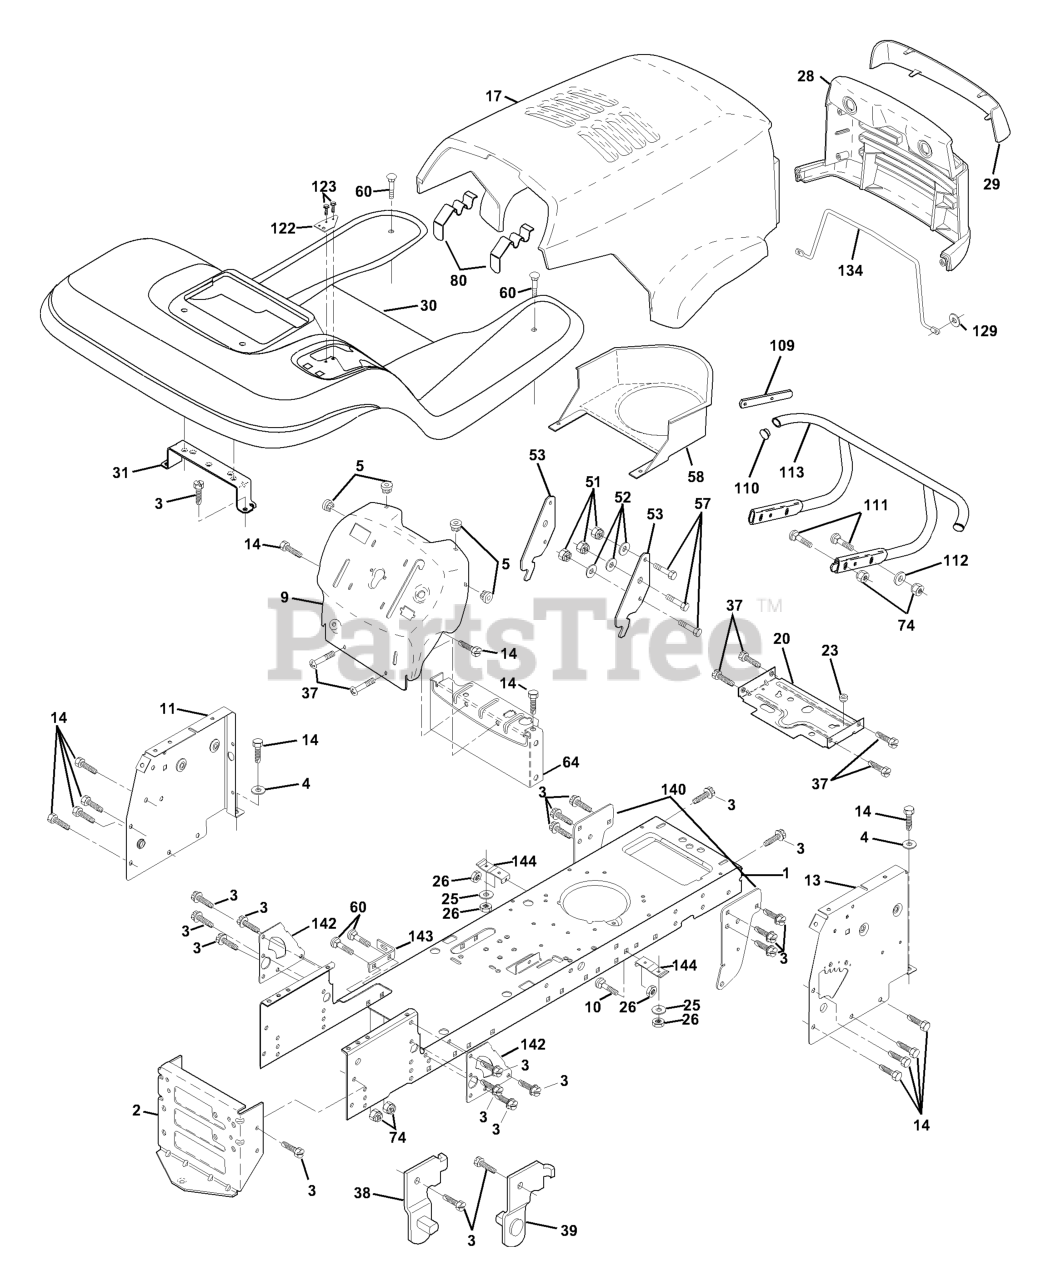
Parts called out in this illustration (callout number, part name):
1	CHASSIS WELDMENT
2	STRETCH DRAWBAR
3	SCREW
4	Washer 13/32 x 3/4 x 16 Ga.
5	BUMPER.RUBBER.HOOD
9	DASH PANEL
10	BOLT D
11	PANEL DASH LH
14	SCREW LT
17	HOOD - LT/YT
20	PLATE MTG
23	BUSHING.SNAP.NYL.BLK.
25	WASHER
26	NUT
28	GRILLE LT/PL HUSQVARNA
29	LENS LT/PL HUSQVARNA
30	FENDER FOOTREST
31	BRACKET.SUPPORT.FENDER
37	Screw Thdrol 6/16-18 x 1/2 TYT
38	BRACKET LH PIVOT
39	BRACKET RH PIVOT
51	LOCKNUT.NYLOC.1/4-20
52	WASHER
53	BRACKET PNT PICK OFF LT/PL
57	BOLT
60	Bolt Rdhd Sqnk 3/8-16unc x 3/4
64	DASH LOWER
80	LATCH HOOD
109	BRACKET BUMPER
110	PLUG PLASTIC
111	Bolt RDHD 3/8-16 UNC x 1-1/2
112	WASHER
113	BUMPER ASM
129	WASHER
134	ROD SUPPORT HOOD LT/PL HUSQ
140	BRACKET CHASSIS FRONT
142	PLATE REINFORCEMENT
143	BRACKET, SWAY BAR
144	BRACKET FOOTREST
146	SCREW TORX HD 5/16X18
